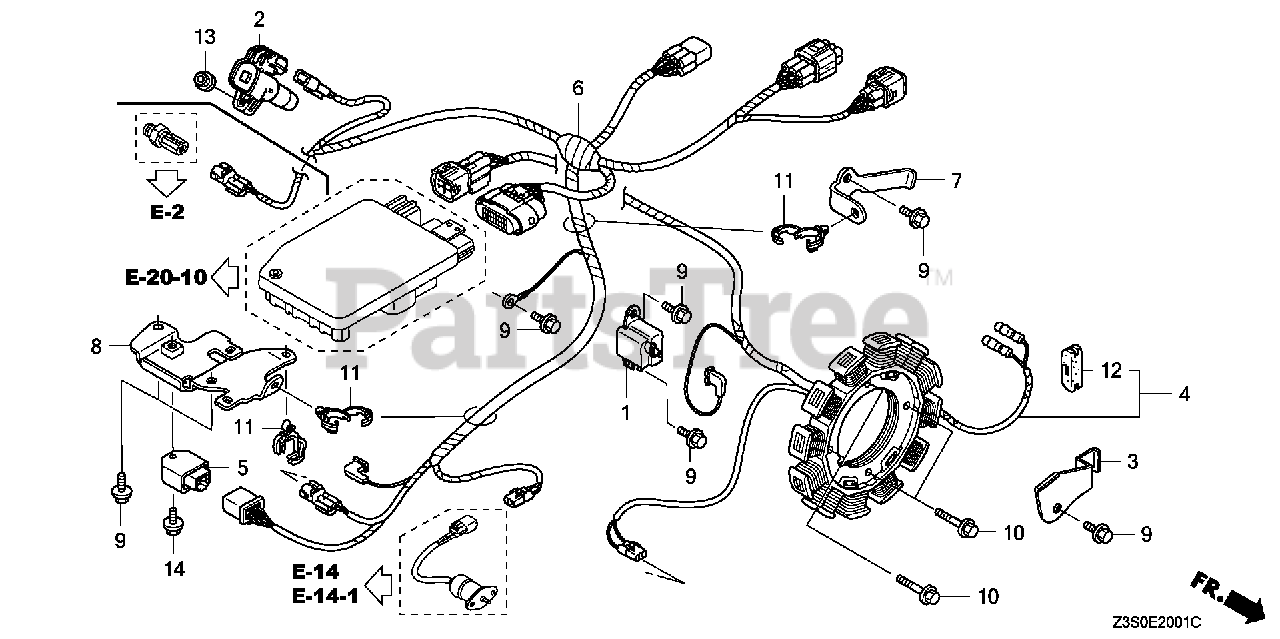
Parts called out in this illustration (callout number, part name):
1	COIL ASSY., PULSER
2	COIL, IGNITION
3	CLAMP, WIRE
4	COIL ASSY., CHARGE (20A)
5	RECTIFIER ASSY.
6	WIRE HARNESS ASSY., ENGINE
7	BRACKET, HARNESS CLIP (A)
8	BRACKET, HARNESS (C)
9	BOLT, FLANGE (6X14)
10	BOLT, FLANGE (6X32)
11	CLIP, HARNESS
12	GROMMET, CORD
13	NUT, FLANGE (6MM)
14	BOLT, FLANGE (6X12) Use from Engine SN 2086984.
